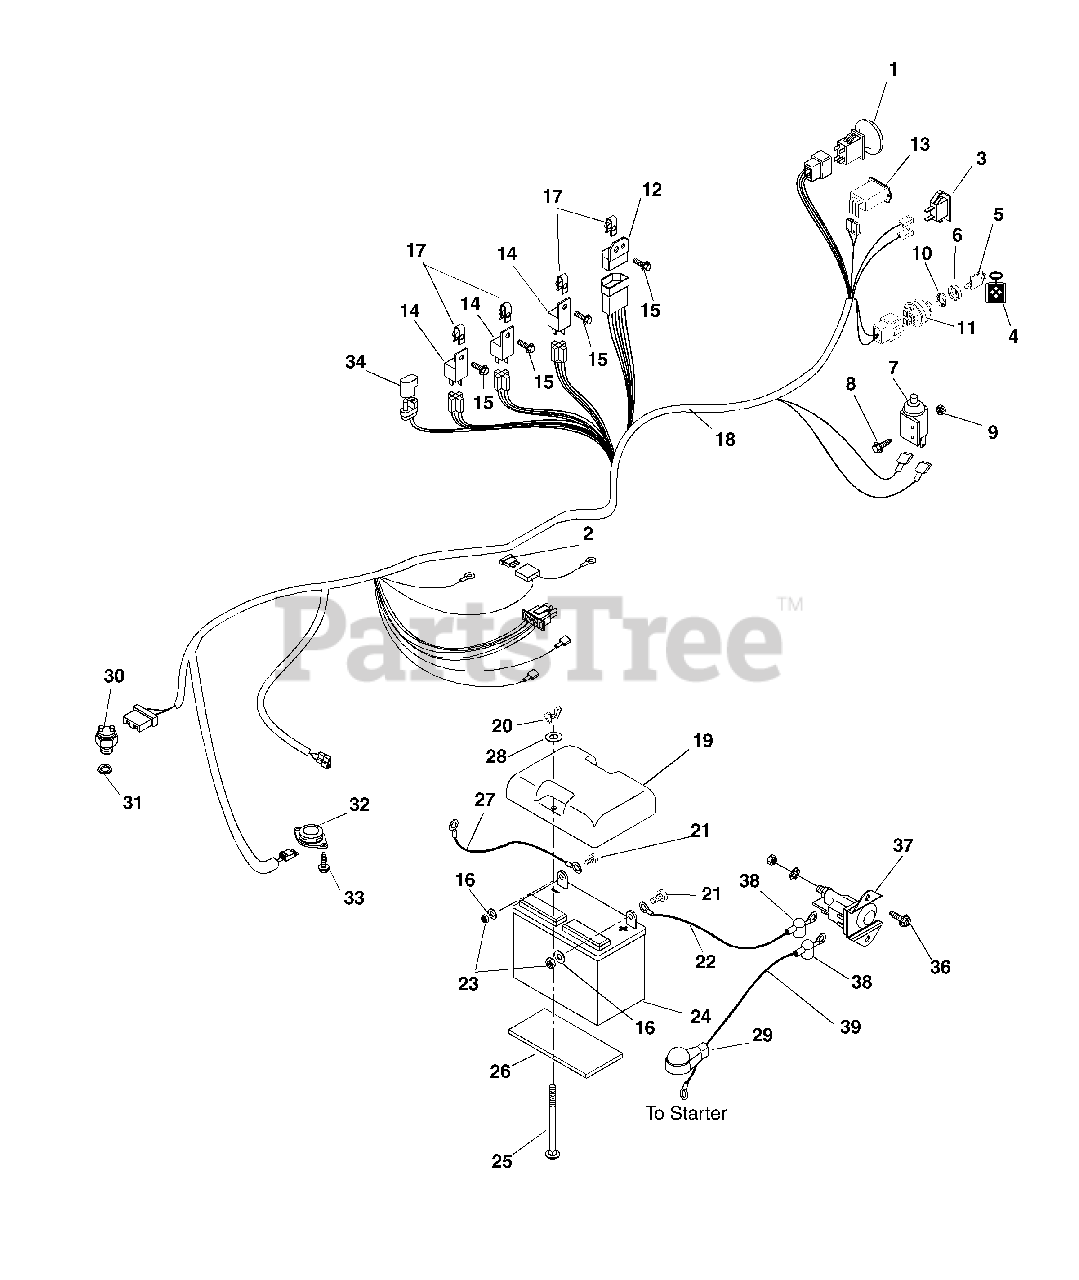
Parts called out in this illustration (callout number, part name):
1	Switch-Clutch with Retainer Ring
2	Fuse, 30 Amp
3	Light-Indicator
4	Key Chain
5	Ignition Switch Key
6	Cap-Ignition Switch
7	Switch-Single Pole (N.O.) with Cover
8	Screw-Machine 10-24 x .50 Hex Washer Head
9	Nut-Locking-Nylon 10-24 with Insert
10	Washer-Lock-Internal .563 x .040
11	Key Switch
12	Module, Time Delay
13	Hour Meter
14	Relay
15	Screw-Machine 10-24 x .75 Hex Washer Head
16	Washer-Flat-Steel .281 x .620 x .065
17	Retainer Nut 10-24
18	Harness-Wiring
19	Cover-Battery
20	Nut-Locking-Wing .250-20
21	Bolt-Hex .25-20 x .75 Grade 5
22	Cable-Starter
23	Nut-Hex .25-20
25	Bolt-Round Head Square Neck .25-20 x 7.00 Grade 2
26	Pad,Battery
27	Cable, Negative Battery 35" Long
28	Washer-Flat-Steel .28 x .62 x .065.
29	Insulator
30	Switch, Neutral Start (N.C.)
31	Nut-Stamped .56-18
32	Switch, Seat
33	Screw-Tapping 12-24X.50 Hex Washer Head
34	Molded Diode Plug
35	Nut-Locking-Center .25-20
36	Screw-Tapping .25-20 x .50 Hex Washer Head
37	Solenoid
38	Boot, Eyelet Terminal
39	Starter Cable 6.75"
